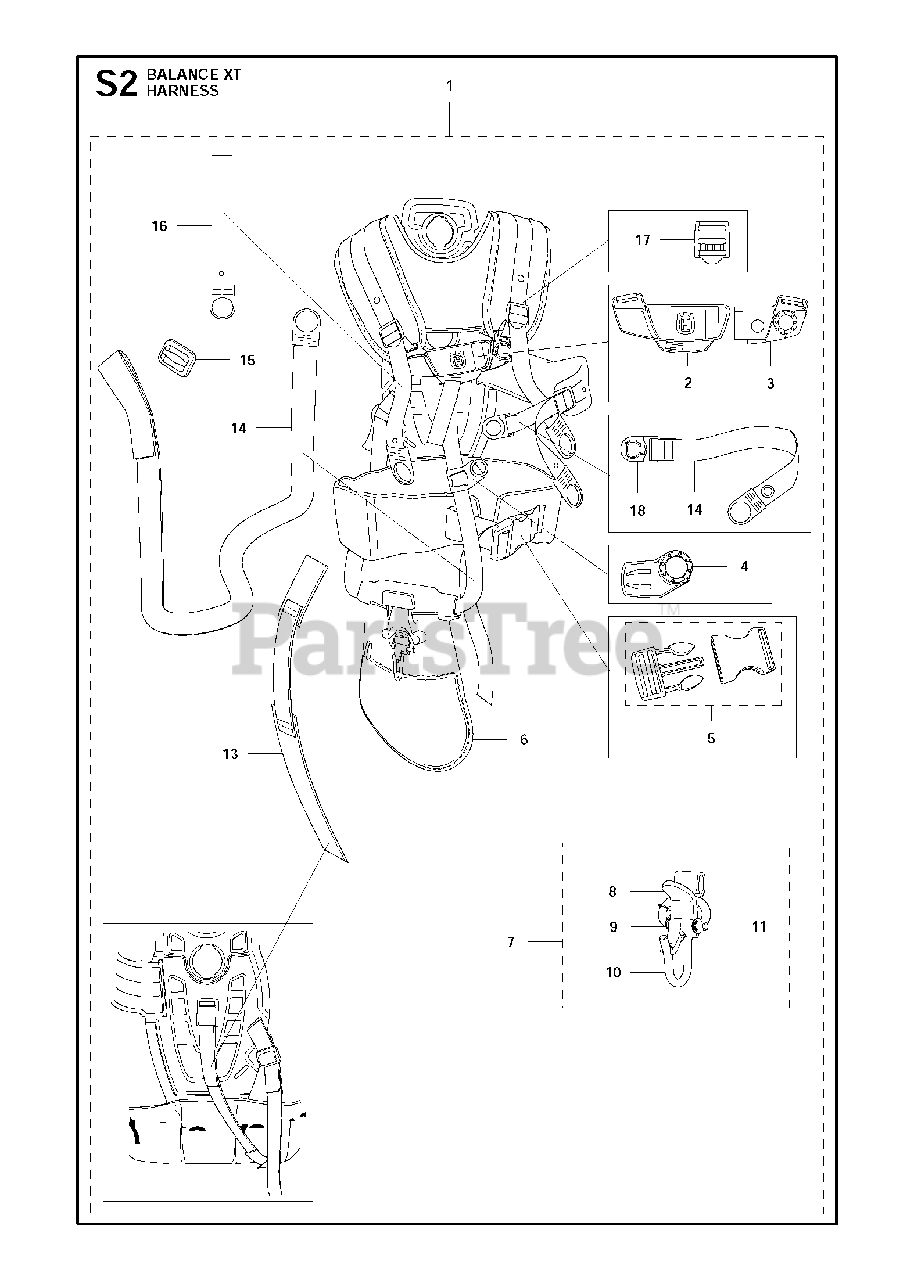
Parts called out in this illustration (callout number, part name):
1	HARNESS BALANCE XT
2	FRONT PIECE
3	FRONT PIECE
4	SNAP LOCKING
5	BUCKLE
6	HIP BAND
7	WELT HOOK
8	CATCH *
9	SPRING LOCKING
10	HOOK
11	E-RING 5
13	BAND
14	BAND
15	RP CLIP
18	SNAP LOCKING
